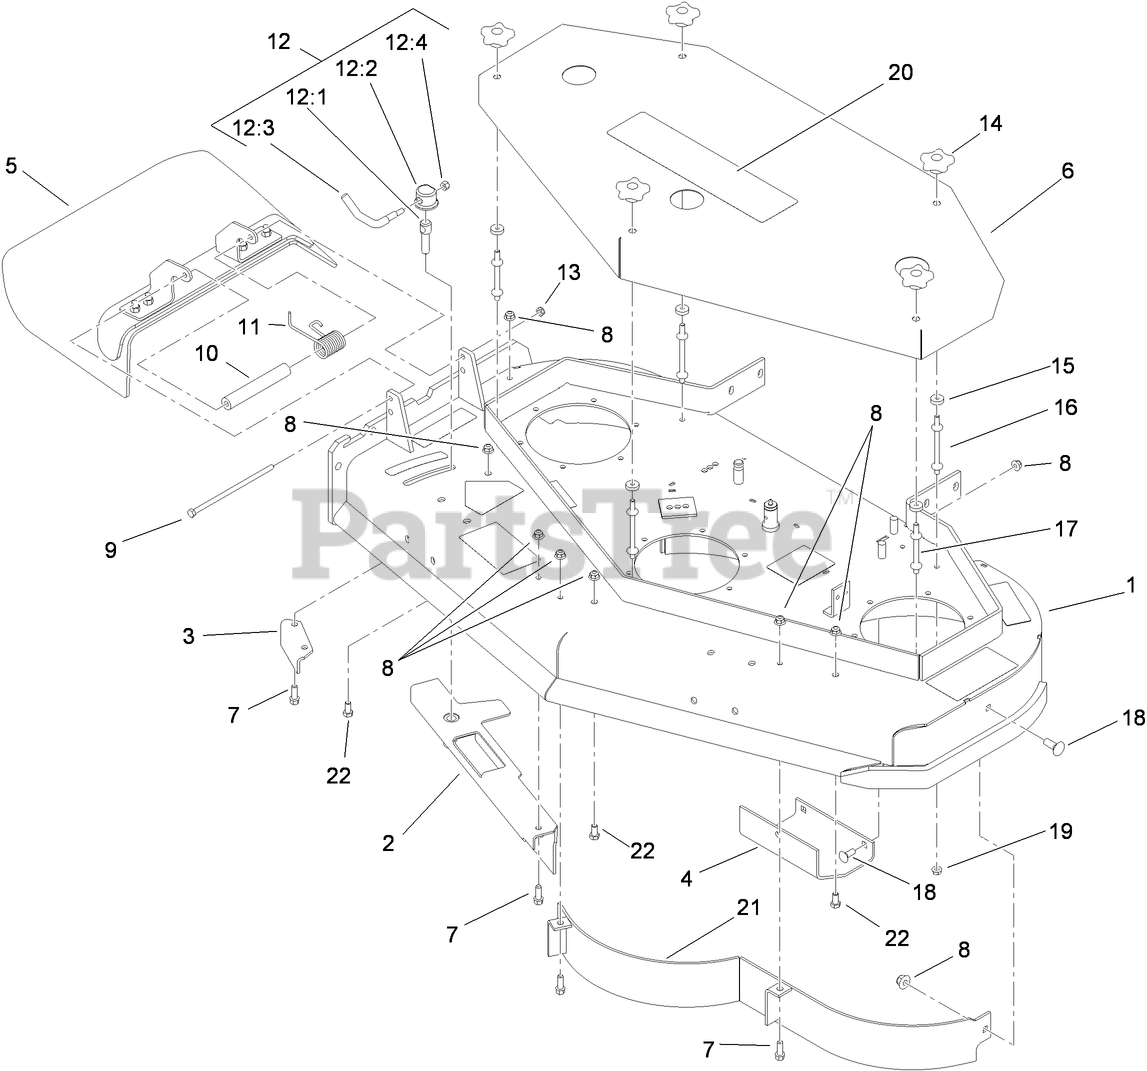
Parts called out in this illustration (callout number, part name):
1	DECK ASM
2	BAFFLE-ADJUSTABLE
3	BAFFLE-DISCHARGE
5	DEFLECTOR ASM
7	SCREW-HWH
8	NUT-HF, NI
9	SCREW-HH
10	SPACER
11	SPRING-TORSION
12	LEVER ASM
12:1	Screw-Lock
12:2	CAP-LOCK
12:3	Lever-Lock
12:4	NUT-LOCK, NI
13	NUT-LOCK, NI
14	KNOB-HANDLE
15	WASHER
16	STUD-SHIELD, BELT (LONG)
17	STUD-SHIELD, BELT (SHORT)
18	BOLT-CARR
19	NUT-HF
22	SCREW-HH
